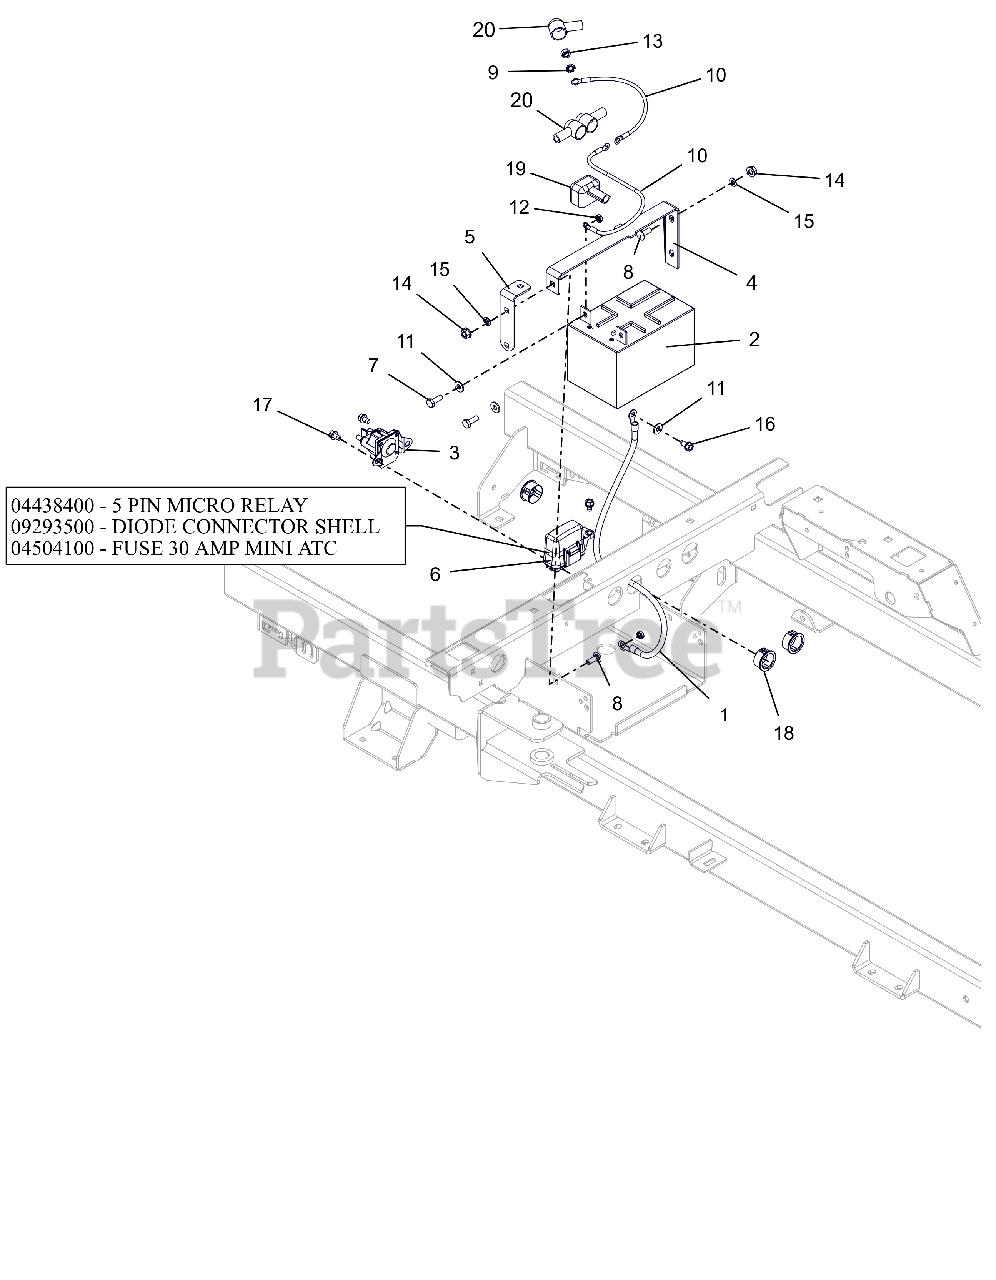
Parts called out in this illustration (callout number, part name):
1	CABLE-NEGATIVE BATTERY 24.00"
2	BATTERY, 12V 12A-190CCA
3	SOLENOID, STARTER (SEALED)
4	BRKT, BATTERY HOLD-DOWN
5	BRKT, BATTERY HOLD DOWN
6	HARNESS, WIRE-4POS KEY IKON/ZT
6	RELAY,MICRO5 TERML W/RESISTOR
6	DIODE, CONNECTOR SHELL
6	FUSE,30 AMP MINI-ATC
7	@BLT-HEX .25-20X.75 GR5 YWZC
8	@BLT-RDHDSQNK .25-20X.75 G5YZ
9	@WSHR-LK-EXT.262X.502X.026YWZC
10	CABLE,POS W/2 1/4 RING 15.0 LG
11	@WSHR-FL-STL.281X.62X.065 YWZC
12	NUT, 10-24 KEPS
13	@NUT-HEX .25-20 YWZC
14	@NUT-LK-TOP-FLG .25-20 YWZC
15	NUT-PUSH .25X.50 O.D.
16	SCR-TAP .25-20X.50 HWH TR YWZ
17	@SCR-TAP .25-20X.37 HWH YWZ TR
18	BSHG, PANEL SNAP .937X1.11X.56
19	INSULATOR
20	BOOT, EYELET TERMINAL
